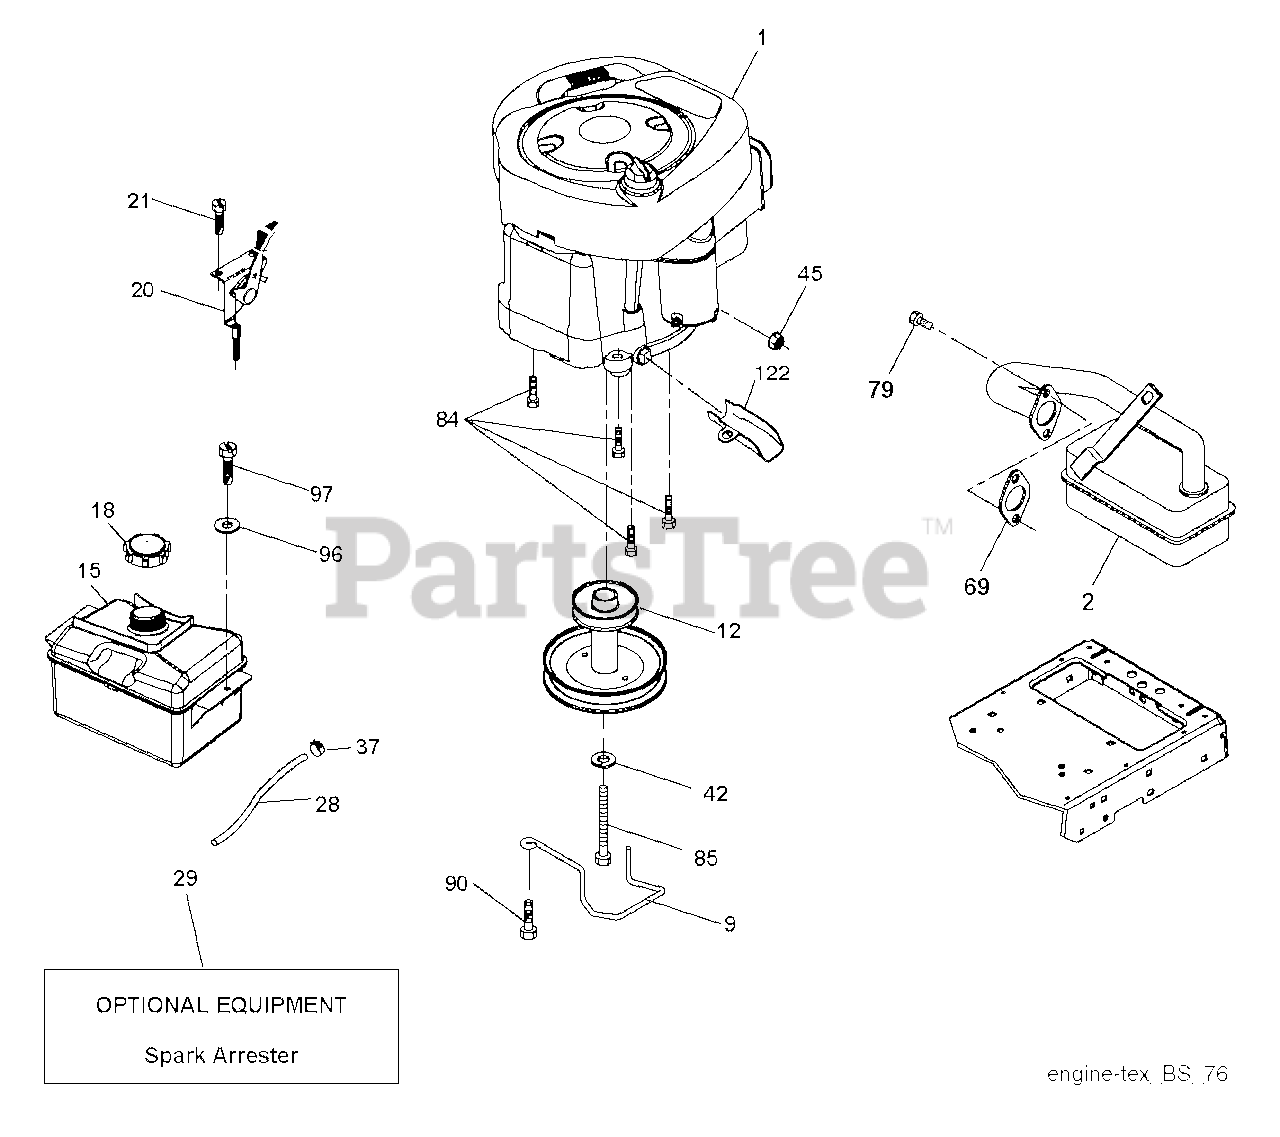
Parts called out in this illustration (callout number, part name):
2	MUFFLER.LT.BRIGGS.14HP.IC/OHV
9	KEEPER.BELT.ENGINE.3.25
12	PULLEY ENGINE
15	FUEL.TANK.ASM.1.5.GAL.NON-EPA
18	CAP.FUEL.2 WAY VENT
21	SCREW.#10 X 0.750.BOS (2 2)
28	LINE.FUEL.20
29	KIT.SPARK ARRESTOR(392390 B&S)
37	HOSE CLAMP
42	LOCKWASHER
45	NUT
79	SCREW.SOCKET HD.5/16-1
84	SCREW.3/8-16
85	BOLT HEX 7/16-20X4-1/4"
90	SCREW 3/8-16X1
97	SCREW HEXWSHR 1/4-20X3/4
122	EXTENSION DRAIN OIL
